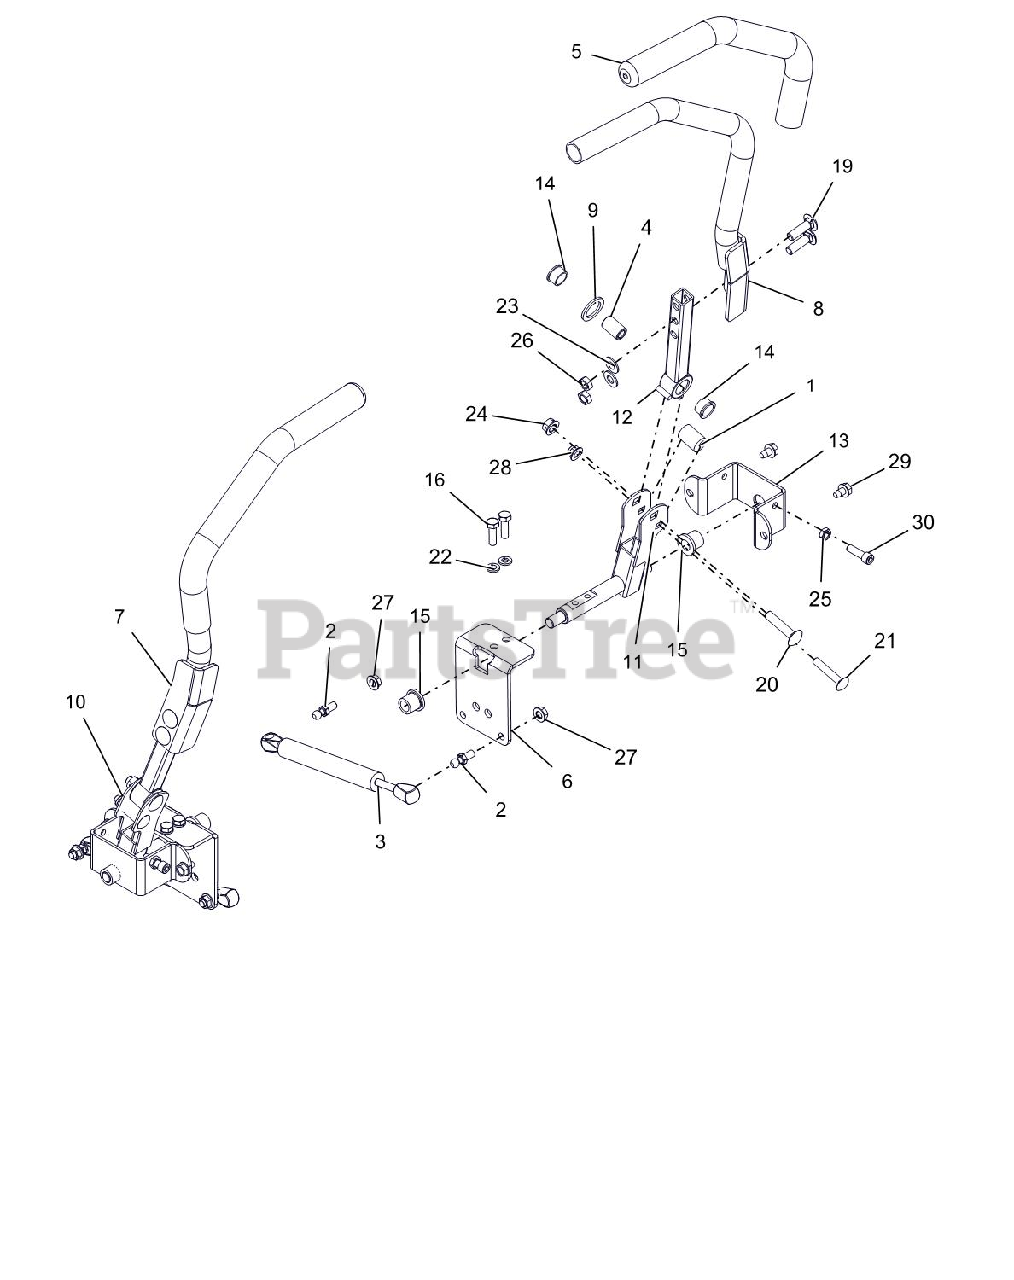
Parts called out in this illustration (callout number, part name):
1	BSHG,ECCEN .328X.750X1.01 PM
2	STUD- BALL
3	DAMPER, STABILUS
4	SPACER, .375X.625X.970 (PM)
5	GRIP, HANDLEBAR 15" FOAM
6	BRKT, STEEERING
7	WLDMT, STEERING HANDLE RH
8	WLDMT, STEERING HANDLE LH
9	WASHER, FRICTION .875X1.25X.10
10	WLDMT,STEERING ARM LOWER RIGHT
11	WLDMT,STEERING ARM LOWER LEFT
12	WLDMT, UPPER CONTROL ARM
13	BRKT, STEERING SUPPORT
14	BSHG-FLG, .625X.75X.450X.875
15	BSHG-FLG .515X.750X.745X1.00NY
16	BLT-HEX .31-18X1.00 GR8 YWZC
19	BLT,RHSSN-.375X1.25 G5 RIE5230
20	BLT,RHSSN-.375X1.75 G5 RIE5230
21	BLT,RHSSN-.312X1.75 G5 RIE5230
22	@WSHR-LK .31X.078 REG YWZC
23	@WSHR-FL-STL.406X.812X.065 YWZ
24	NUT-LK-CTR-FLG .38-16 YWZC
25	NUT- JAM .312-18 YWZC
26	@NUT-LK-CTR-JAM .375-16 YWZC
27	@NUT-LK-TOP-FLG .31-18 YWZC
28	@NUT-LK-NYL-FLG .31-18 YWZC
29	@SCR-TAP .31-18X.50 HWH TR YWZ
30	SCR, SKH .312-18X1.00 G8 ZC120
